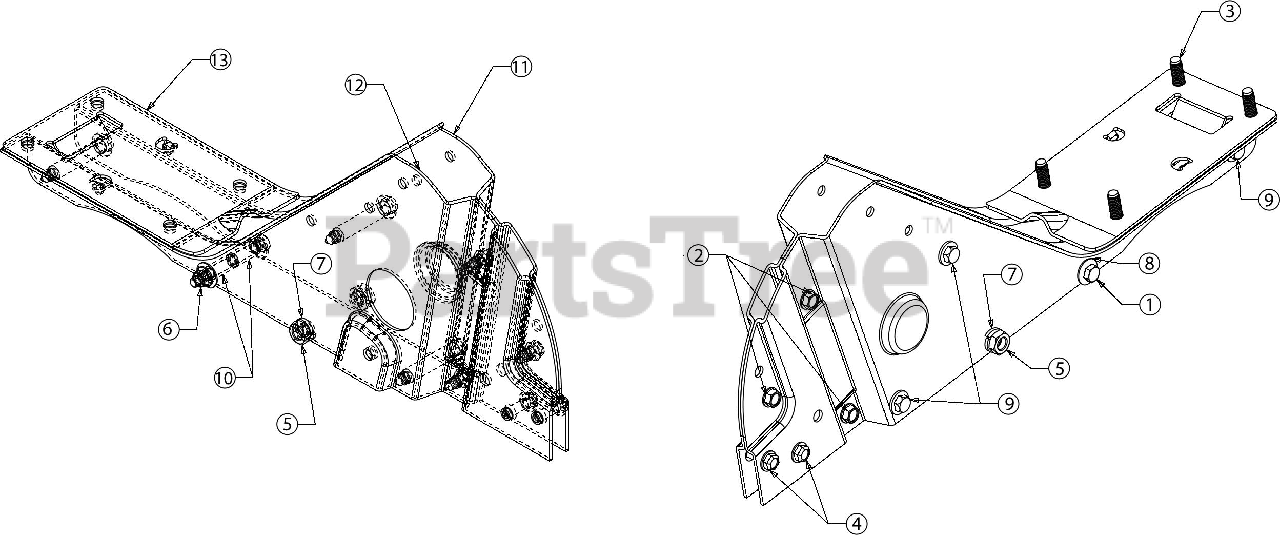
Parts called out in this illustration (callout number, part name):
1	HEX SCREW 5/16-18 X 3.00
2	SCREW 5/16-18 X .750
3	SCREW 3/8-16 X 1.250
4	SCREW 5/16-18 X 1.00
5	JAM NUT 7/16-20
6	FLANGE LOCK NUT 5/16-18
7	LOCK WASHER 7/16
8	BELL WASHER .337 X.867 X .057
9	SHOULDER BOLT .5/16X18
10	SPACER
